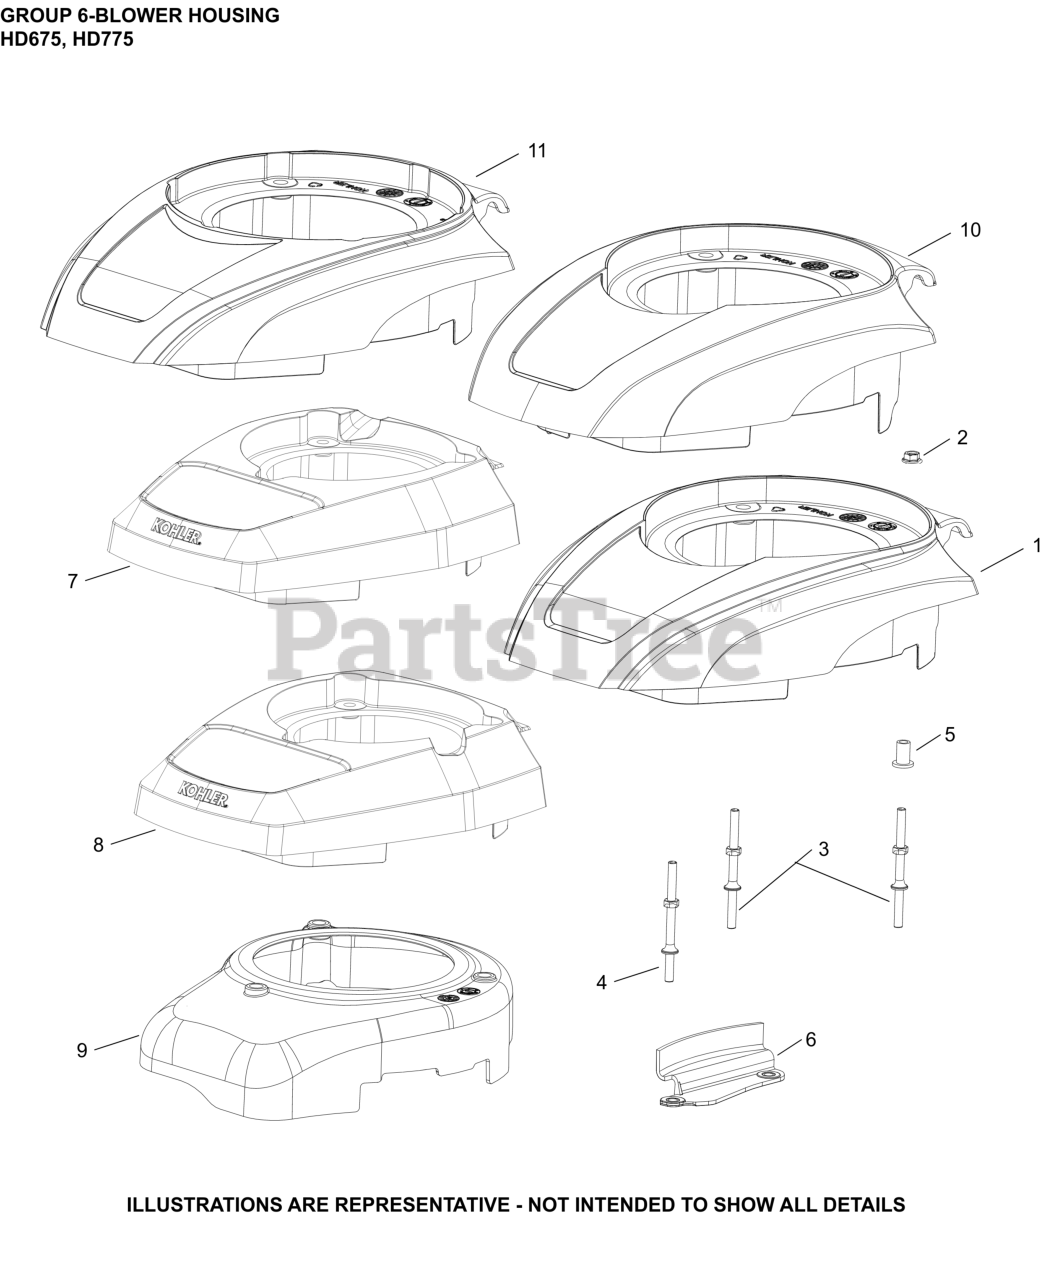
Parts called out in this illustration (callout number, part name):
1	COVER, ENGINE
2	NUT, HEX FLANGE (M6) - USE 14 100 16-S
3	STUD-USE 14 072 25-S
4	STUD-USE 14 072 26-S
6	GUARD, FINGER
